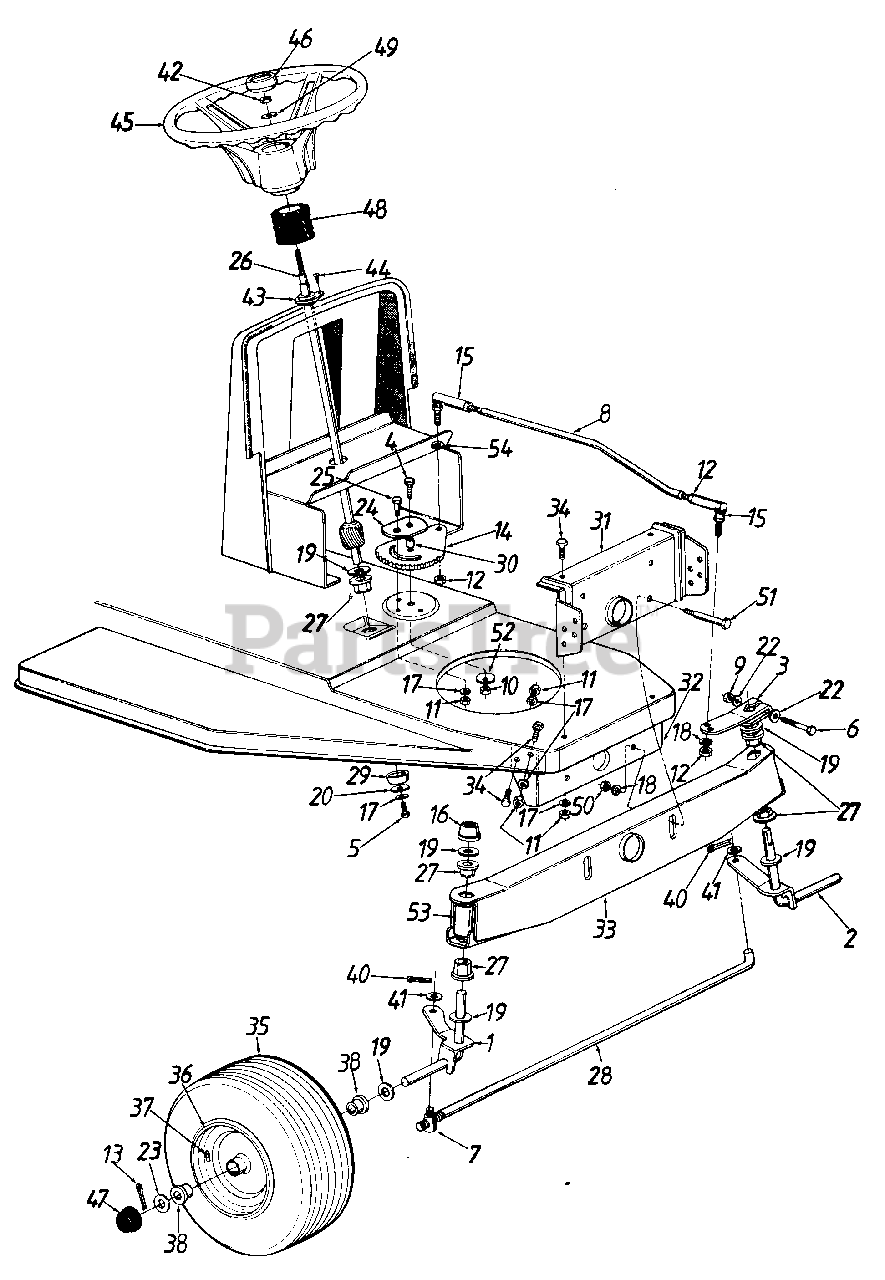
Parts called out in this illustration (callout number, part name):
1	Front Axle Ass'y.-R. H .
2	Front Axle Ass'y.-L.H.
3	Steering Arm
4	Hex Bolt 3/8-24 x 1" Lg.*
5	Hex Bolt 5/16-18 x .62"
6	Hex Bolt 5/16-24 x 2" Lg.
7	Ferrule
8	Steering Drag Link
9	Hex L-Nut 5/16-24 Thd.
10	Hex Nut 3/8-24 Thd.
11	Hex Nut 5/16-18 Thd.
12	Hex Jam Nut 3/8-24 Thd.
13	Cotter Pin 1/8" Dia.
14	Steering Gear Segment
15	Drag Link Ball Joint 3/8-24 Thd.
16	Push Cap
17	L-Wash. 5/16" I.D.
18	L-Wash. 3/8" I.D.
19	Fl-Wash. .64" I.D. x 1.24"
20	Fl-Wash. .340" I.D. x 1.125"
22	Spr. Wash. .32" I.D. x .62"
23	Fl-Wash. .635" I.D. x 1.585"
24	Retainer Plate
25	Shld. Bolt .437" Dia. x .350"
26	Steering Shaft
27	Hex Flange Brg. .634" Dia.
28	Tie Rod 19.1" Lg.
29	Spacer.985" I.D.
30	Spacer.380" I.D.
31	Front Pivot Bar Support Brkt.
32	Rear Pivot Bar Support Brkt.
33	Pivot Bar Ass'y.
34	Hex Bolt 5/16-18 x .62" Lg.
35	Front Wheel Ass'y. Comp. 13" x6"
37	Air Valve
38	Flange Bearing .632" I.D.
40	Cotter Pin 3/32" Dia.
41	Fl-Wash. .406" I.D. x .75"
42	Hex L-Nut 5/16-24 Thd.
43	Steering Column Brg.
44	Cr-Sunk Scr. #10 x 5/8" Lg.
45	Steering Wheel
46	Steering Wheel Cap
47	Hub Cap
48	Bellow Steering Column
49	Bell-Wash. .345" I.D. x .88"
50	Hex Nut 3/8-16 Thd.
51	Shld. Bolt 1/2" Dia. x 2.32"
52	Bell-Wash. .39" I.D. x 1.4" O.D.
53	Plastic Tube
54	L-Wash. 3/8" I.D. (H.D.)
